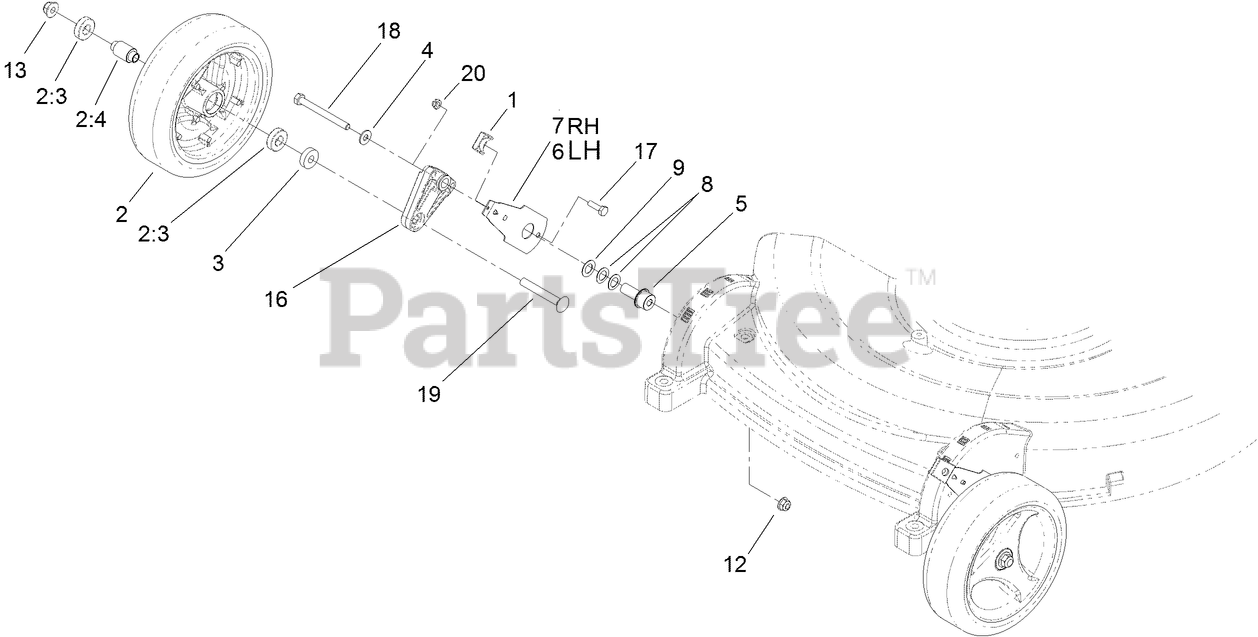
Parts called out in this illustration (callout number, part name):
1	KNOB-ARM
2	8 INCH WHEEL ASM
2:3	BEARING-WHEEL
2:4	SPACER-WHEEL, FRONT
3	SPACER
4	WASHER-FLAT
5	BUSHING-PIVOT, WHEEL
6	LH FRONT SPRING ARM ASM
7	RH FRONT SPRING ARM ASM
8	WASHER-CONICAL
9	WASHER-PLAIN
12	NUT-HF, NI
13	NUT-HF, NI
16	ASM-FRONT WHEEL ARM
17	SCREW-HH
18	SCREW-HH
19	SCREW-CARR
20	NUT-LOCK, NI
